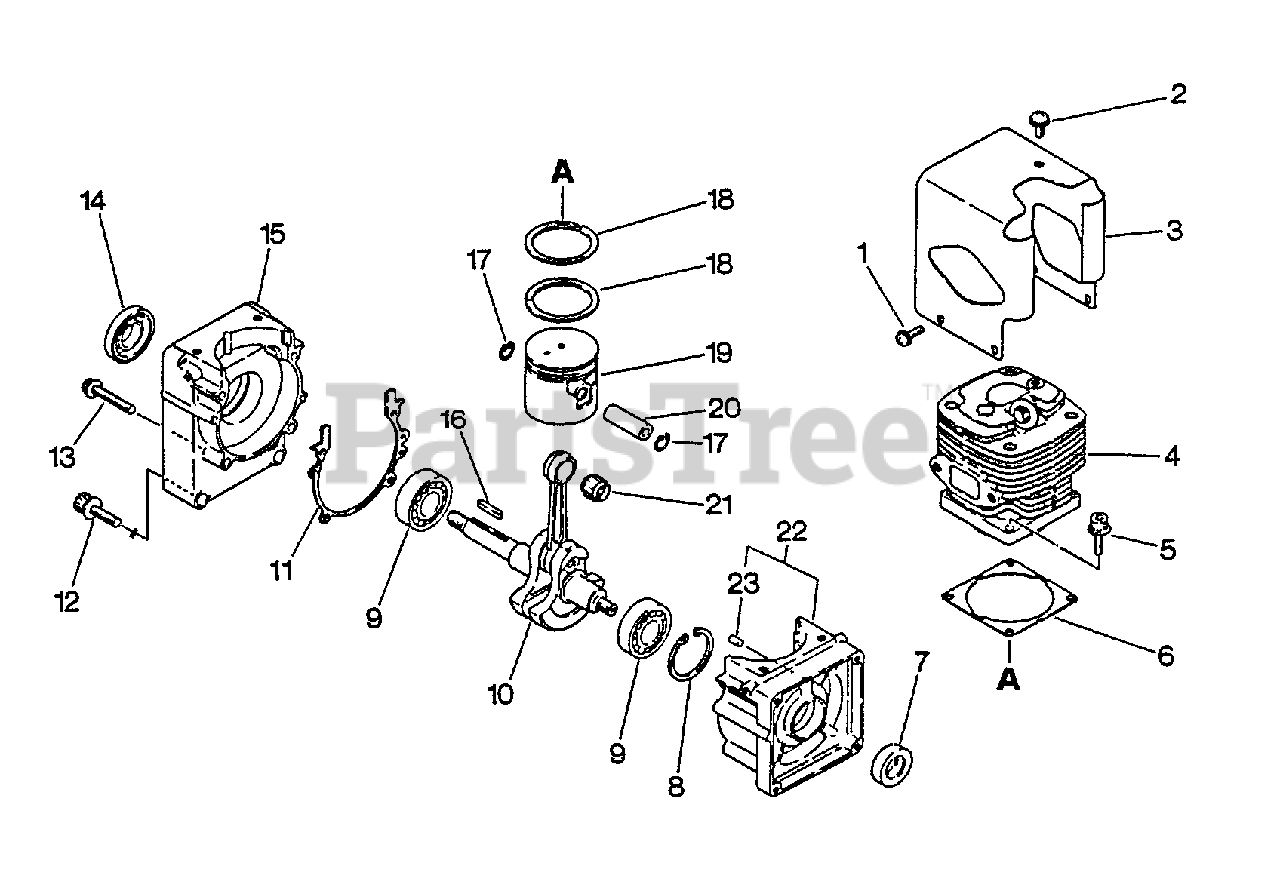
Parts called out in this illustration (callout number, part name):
1	SCREW 4×10
2	SCREW 5×10
3	COVER, CYLINDER - BLACK
4	CYLINDER
5	BOLT 5×20
6	GASKET, CYLINDER
7	SEAL, OIL
8	RING, SNAP 35
9	BEARING, BALL 6202
10	CRANKSHAFT ASSY
11	GASKET, CRANKCASE
12	BOLT 6×20
13	SCREW 5×30
14	SEAL, OIL 18
15	CRANKCASE KIT
17	RING, SNAP 8
18	RING, PISTON
20	PIN, PISTON
21	BEARING, NEEDLE
22	CRANKCASE KIT
23	PIN, LOCATING 4
